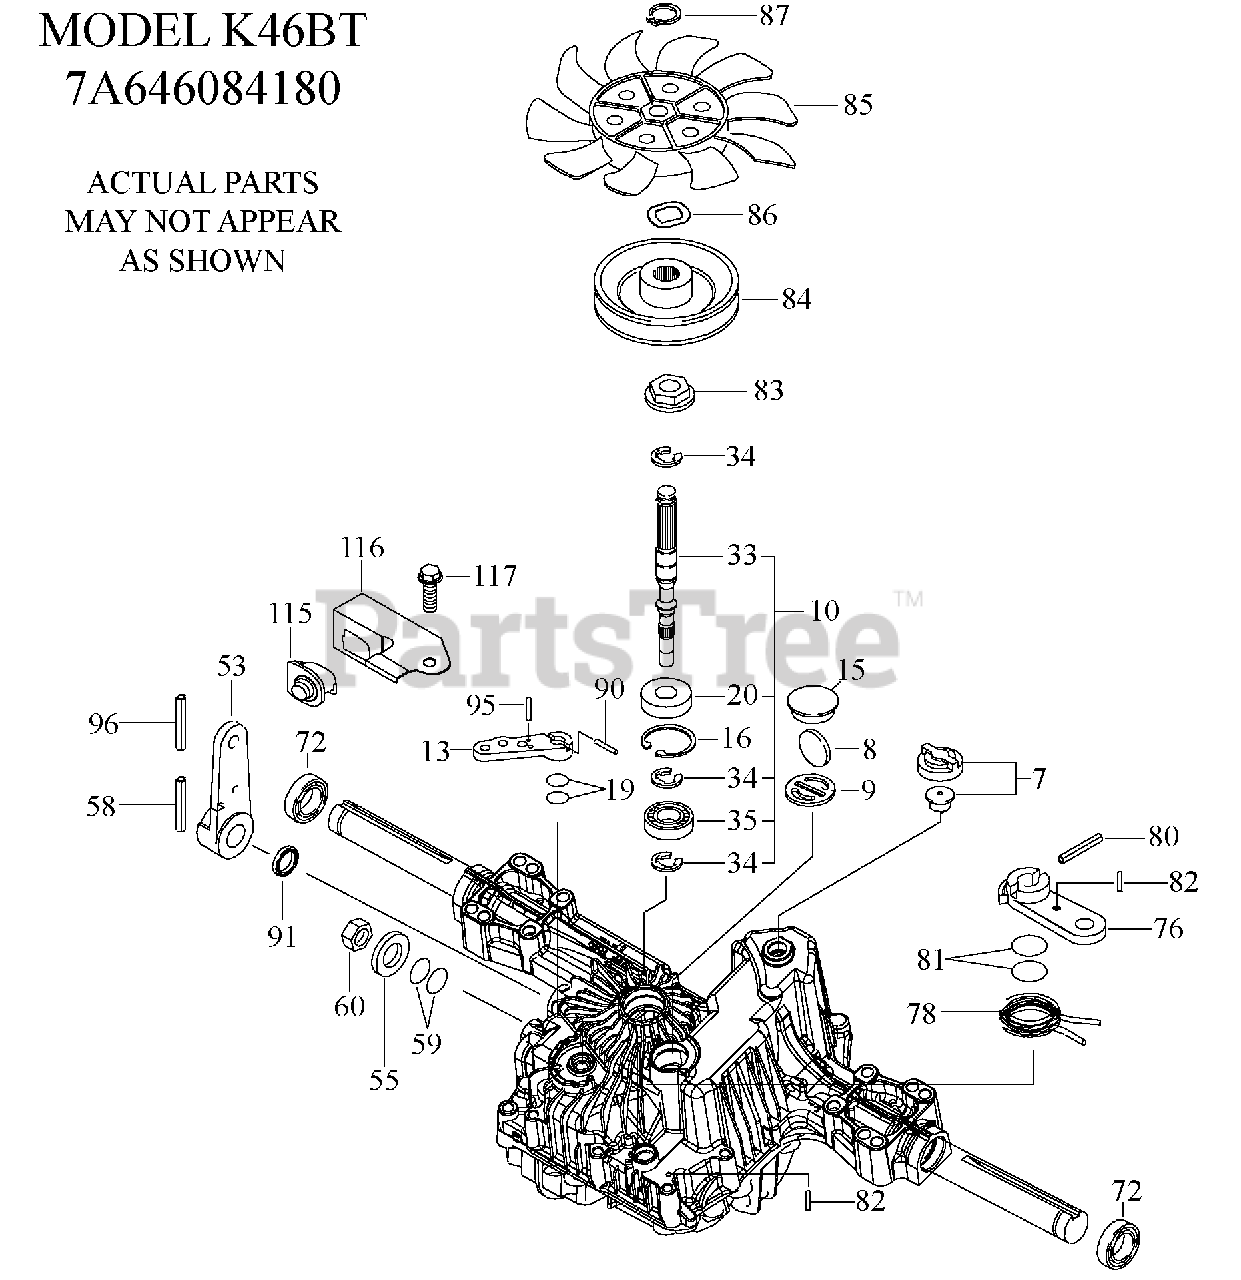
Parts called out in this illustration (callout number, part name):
7	Vent Valve 15
8	Magnet
9	Magnet Holder
10	Pump Shaft/Bearing Kit
13	Bypass Lever
15	Sealing Cap 30
16	Snap Ring C 35
19	O-Ring 1A P10A
20	Seal Tc 153507
33	Pump Shaft (Standard)
34	E-Ring 15
35	Bearing 6202C3
53	Control Lever F
55	Washer 12
58	Roll Pin 6 x 40
59	O-Ring 1A P14
72	Seal 19 x 32 x 8
76	Brake Lever
78	Brake Return Spring
80	Spring Pin 5 x 32
81	0-Ring 1A P12
82	Spring Pin 4 x 16
83	Spine Collar
84	Pulley L
85	Fan, Black
86	Wave Washer
87	Snap Ring
90	Spring Pin 3.0A x 20
91	Oil Seal 16 x 22 x.03
95	Spring Pin 3.0Ax16
96	Roll Pin 3.5 x 40
115	Switch 6440-11 Delta
116	Switch Bracket
117	Tapping Screw 8 x 20
